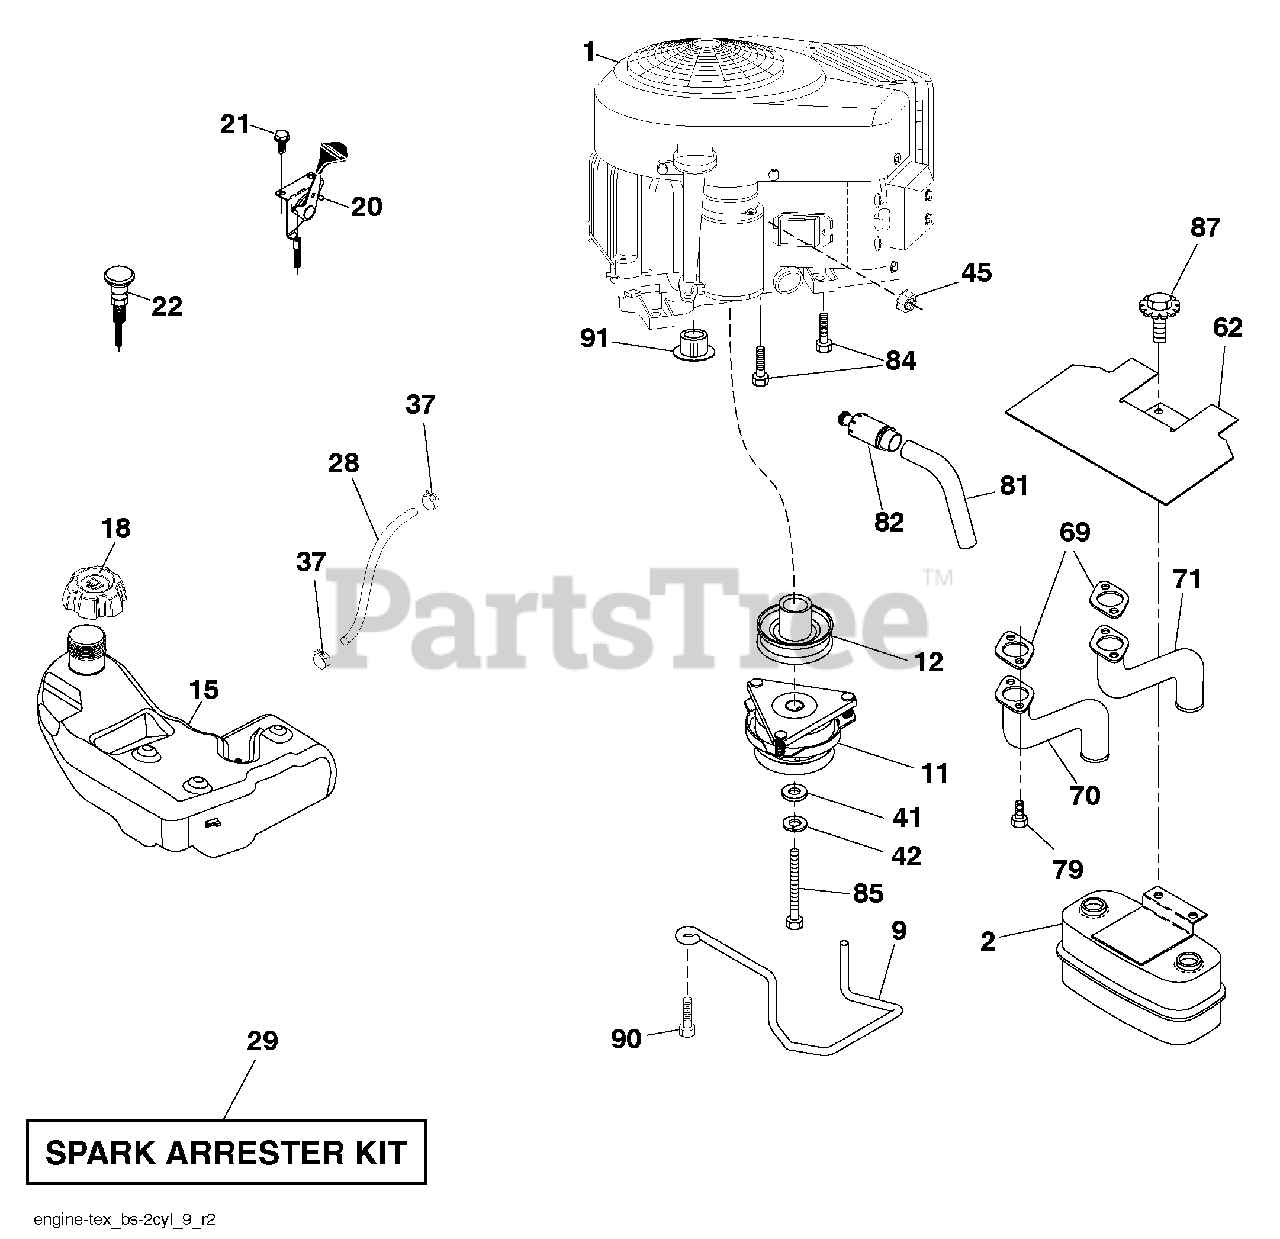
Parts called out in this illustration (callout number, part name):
2	Muffler
9	Keeper Belt Engine
11	Clutch Electric
12	Pulley Engine
15	Tank Fuel
18	Cap Asm.
20	Control Throttle
21	Screw #10 x 0.750 BOS Thread
22	Control Choke
28	Fuel Line
29	Spark Arrester Kit
37	Clamp Hose
41	Washer 1-1/2 OD x 15/32 ID x .250
42	Washer Lock 7/16
45	Nut Keps Hex 1/4-20 unc
62	Shield Heat Muffler
69	Gasket
70	Exhaust Tube LH
71	Exhaust Tube RH
79	Screw Socket Head 5/16-18 x 1
81	Tube Drain Oil Easy
82	Plug Drain Oil
84	Screw 3/8-16 x 1-1/4
85	Bolt Hex 7/16-20 x 3.75 Gr. 5
87	Bolt 5/16-18 x 1
90	Screw 3/8-16 x 1
91	Bushing 1.375 OD
